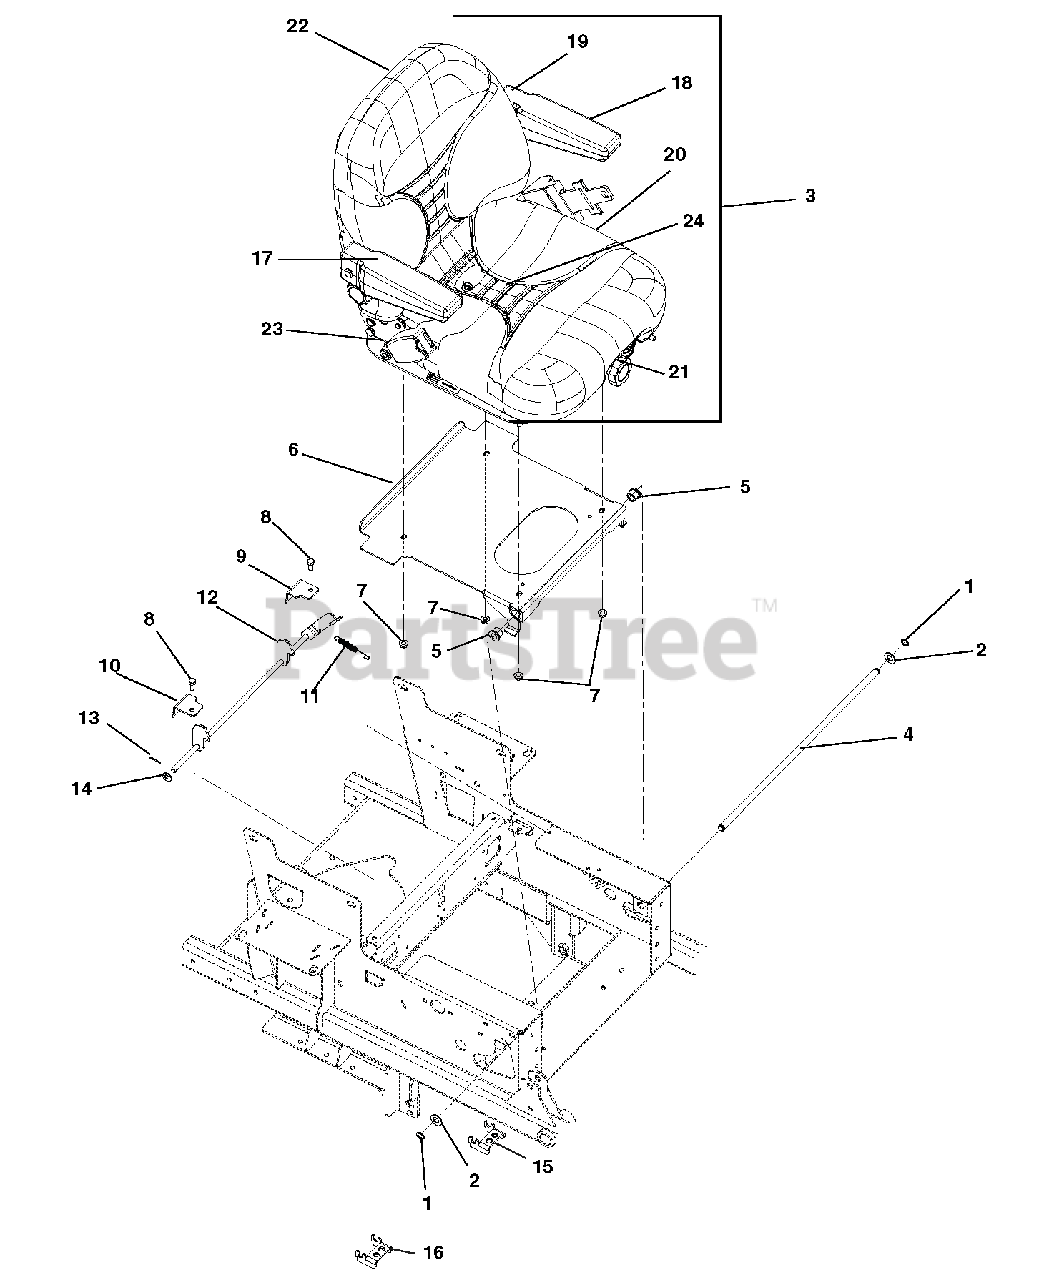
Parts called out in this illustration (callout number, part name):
1	RG-RTNG-EXT .500X.050 (SNAP)
2	WSHR-FL-STL.531X1.00X.063 YWZC
3	SEAT,SUSP,W/SEAT BELT,LT GRY
4	SHAFT, PT100 SEAT PIVOT
5	BSHG, FLG .516X.750X.625X.937
6	PRO-TURN100 SEAT PLATE WMT-BLK
7	@NUT-LK-NYL-FLG .31-18 YWZC
8	@BLT-HEX .31-18X.75 GR5 YWZC
9	PT100 LH TOP SEAT LATCH MNT-BL
10	PT100 RH TOP SEAT LATCH MNT-BL
11	SG-TENS .043X.44X3.31 WLD 5.8
12	PRO-TURN100 SEAT LATCH WMT-BLK
13	@PIN-CTR .09X.75 EXTPRSQCT YWZ
14	@WSHR-FL-STL.406X.812X.065 YWZ
15	PT100 RH SEAT LATCH MNT WMT-BL
16	PT100 LH SEAT LATCH MNT WMT-BL
17	KIT-RH ARMREST ASSEMBLY REPLAC
18	KIT-LH ARMREST ASSEMBLY REPLAC
19	KIT-BACK CUSHION-LIGHT GRAY
20	KIT-SEAT CUSHION-LIGHT GRAY
21	KIT-SEAT KNOB
22	KIT-SEAT BACK PANEL
23	KIT-SEAT SLIDE
24	KIT-SPRING AND SADDLE
